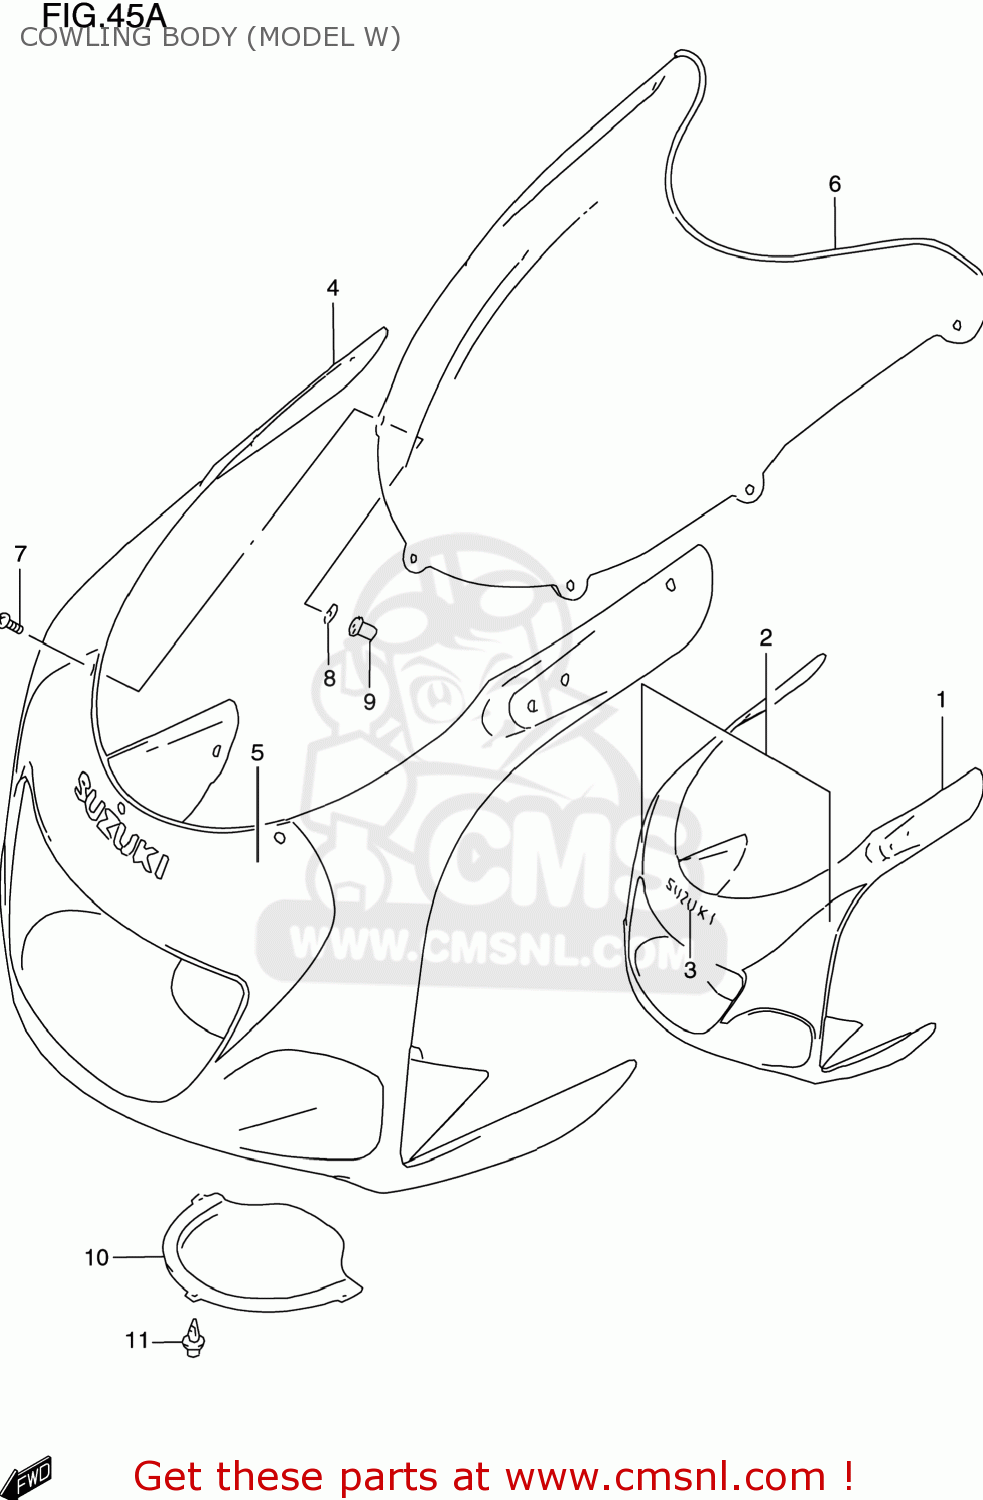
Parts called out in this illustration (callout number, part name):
1	COWLING ASSY,BODY
2	TAPE SET,COWL BODY
3	EMBLEM,FR
4	COWLING ASSY,BODY
5	TAPE SET,COWL BODY
6	WINDSCREEN
7	SCREW(5X14)
8	WASHER
9	NUT
10	LID,BODY COWL LWR
11	CLIP(BLACK)
